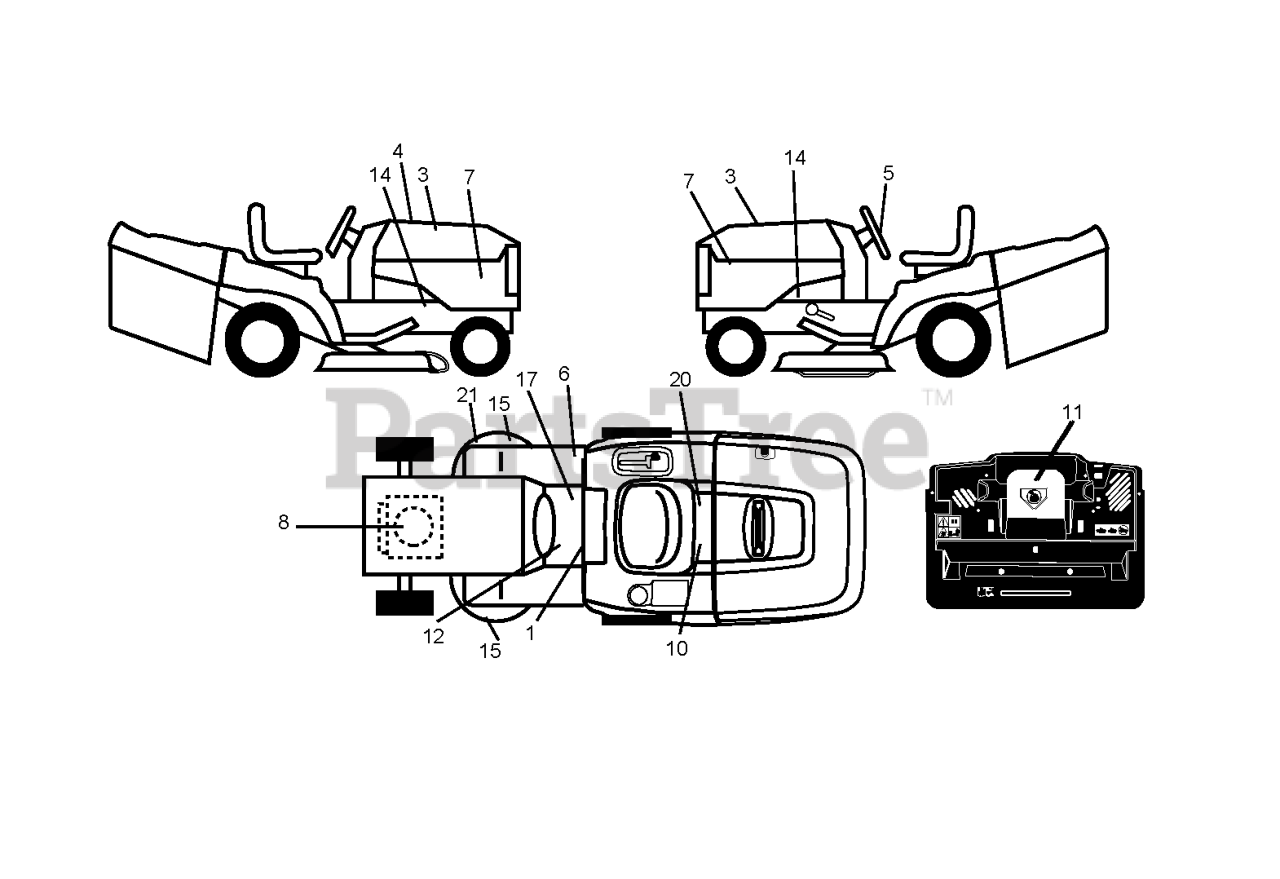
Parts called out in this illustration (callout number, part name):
1	LABEL
3	DECAL.HOOD.NAMELOGO.HUSQ
5	DECAL.WHEEL.STRG.LGN.H
6	Decal, Fender 100 DB/CE
8	DECAL
10	DECAL BTRY SYMBOLS
11	DECAL.INTERNATIONL.CUTFINGER
12	DECAL
17	DECAL PARK BRAKE
20	DECAL.BYPASS.FENDER.CRD.LT.YT
